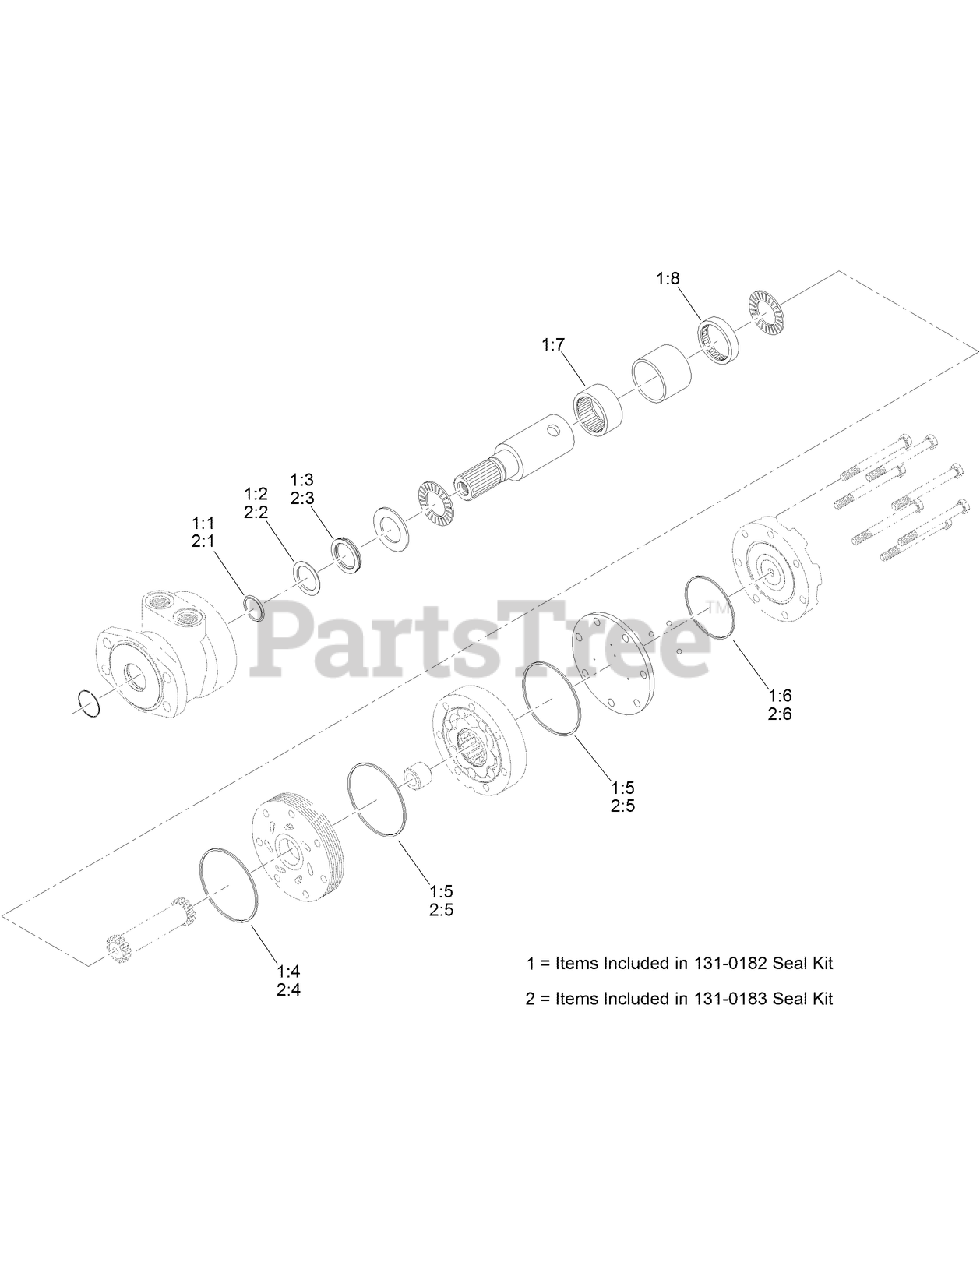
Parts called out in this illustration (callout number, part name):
1	SEAL KIT
1:1	SEAL-EXCLUDER
1:2	Seal-Backup
1:3	SEAL-Shaft
1:4	SEAL-HOUSING
1:5	SEAL-BODY
1:6	SEAL-ENDCOVER
1:7	BEARING-HOUSING, FRONT
1:8	BEARING-HOUSING, REAR
2	SEAL KIT
2:1	SEAL-EXCLUDER
2:2	Seal-Backup
2:3	SEAL-Shaft
2:4	SEAL-HOUSING
2:5	SEAL-BODY
2:6	SEAL-ENDCOVER
